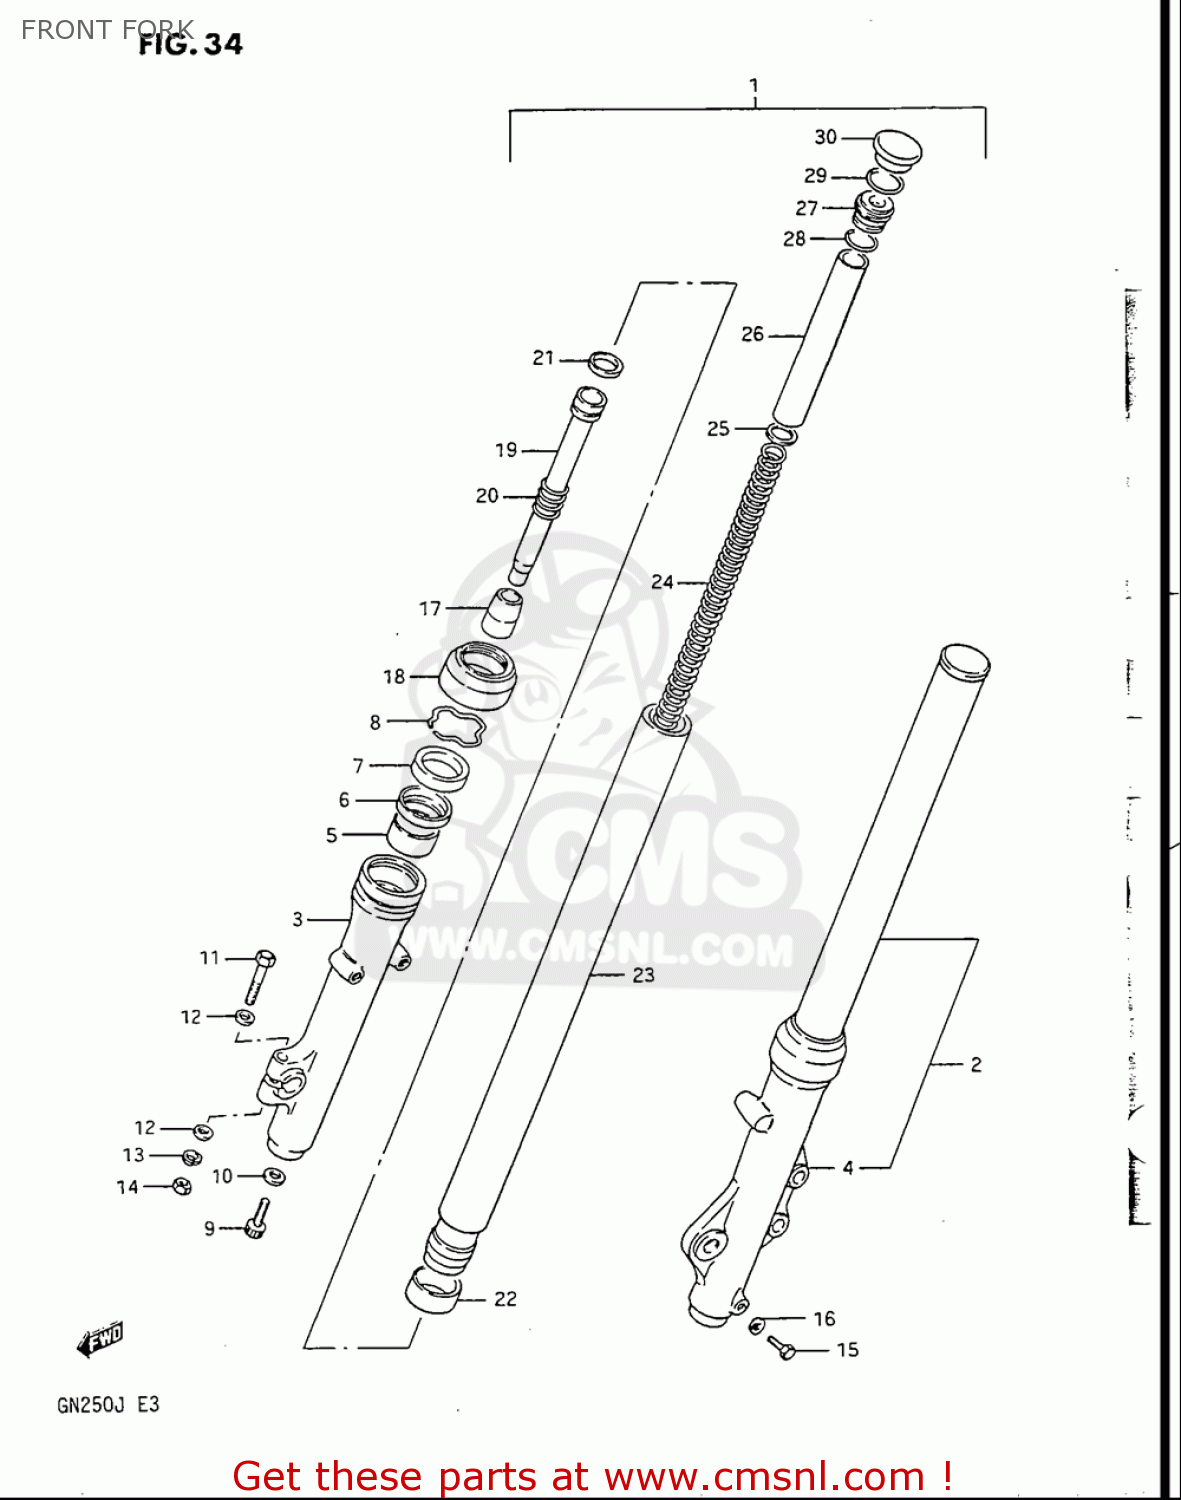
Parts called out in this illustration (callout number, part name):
2	DAMPER ASSEMBLY,LEFT
3	TUBE,FORK,OUTER,RIGHT
5	BUSH,GUIDE
6	SPACER,OIL SEAL
7	SEAL,OIL
8	RING,OIL SEAL STOPPER
9	BOLT(8X27)
10	GASKET (NAS)
11	BOLT
12	WASHER
13	WASHER,LOCK
14	NUT
15	BOLT(6X8)
16	GASKET,DRAIN,PLUG (NAS)
18	DUST SEAL
22	BUSH
23	TUBE,INNER
26	SPACER,FRONT FORK SPRING
27	SEAT,SPRING
28	O RING
29	STOPPER RING FO
30	CAP
